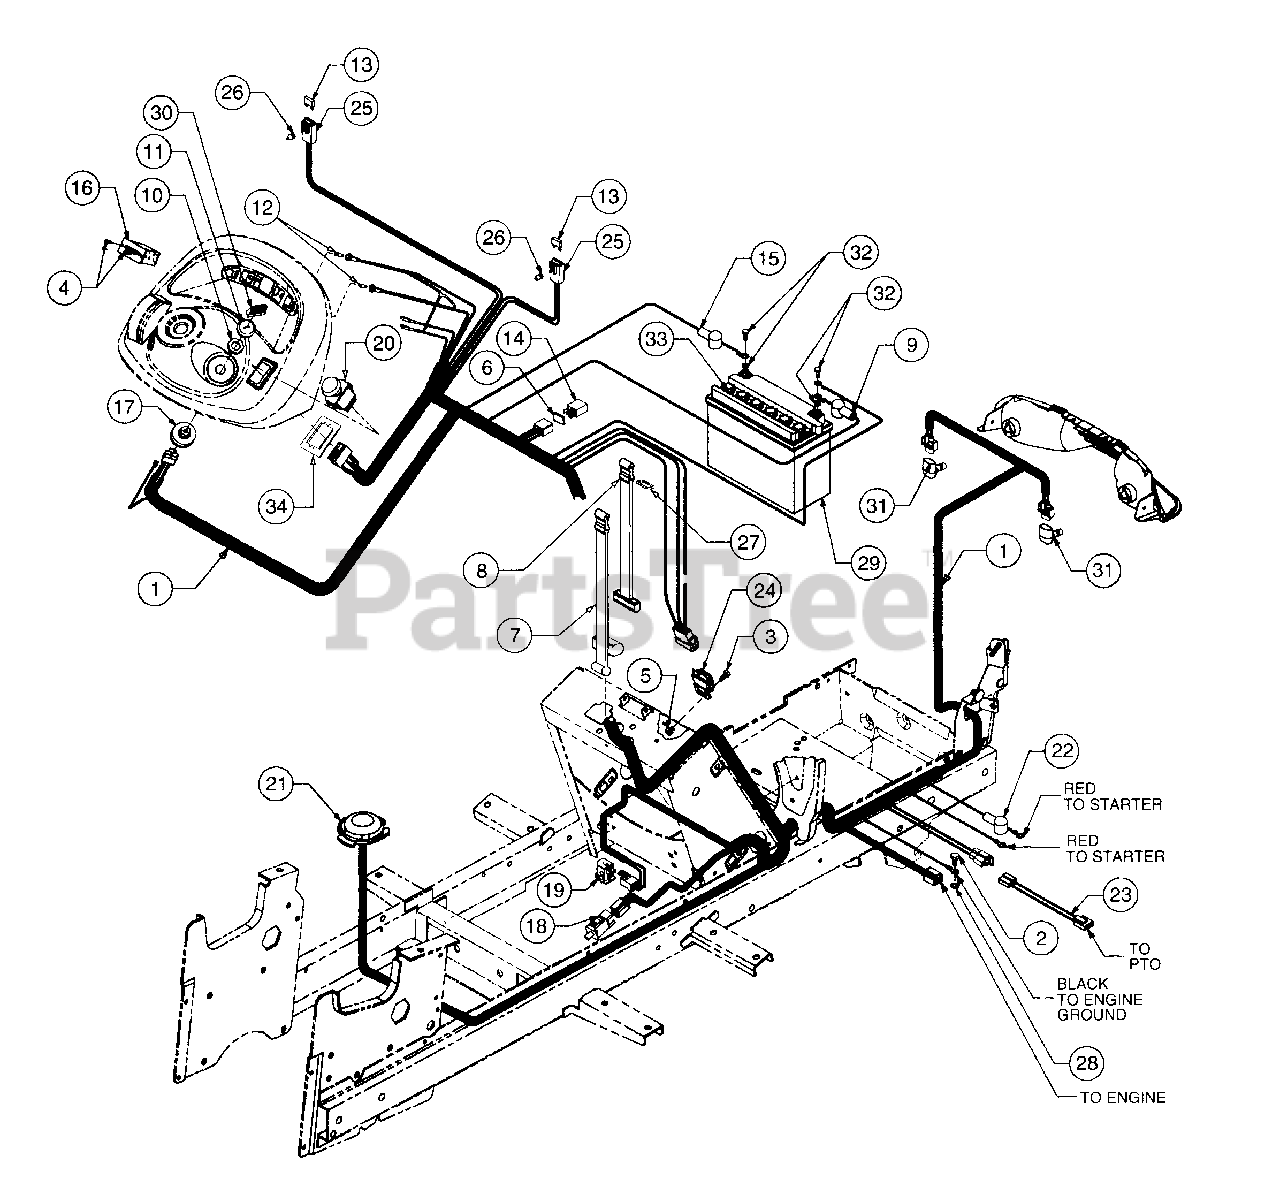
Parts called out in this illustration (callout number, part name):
1	Wire Harness, Main
2	Screw, Hex Cap, 5/16-24 x .62
3	Screw, Hex Cap, 1/4-20 x .625 GR5
4	Screw, Truss Hd Tapp, #6 x .62
5	Nut, Hex Sems, 1/4-20
6	Gasket, Silicone
7	Strap, Battery Retainer
8	Strap, Battery Retainer
9	Cover, Terminal Black
10	Nut, Ignition Switch
11	Cap, Ignition Switch
12	Bulb, Indicator
13	Fuse, 20 Amp
14	Relay
15	Cover, Terminal Red
16	Hour Meter
17	Switch, Ignition
18	Switch, Interlock (Brake)
19	Switch, Snap Mount - Normally Closed
20	Switch, PTO
21	Switch, Seat
22	Cover, Terminal Red
23	Adapter, PTO Harness
24	Module, Voltage Sensor
25	Holder, Fuse
26	Clip, Fuse Holder Mounting
27	Hook, Wire Rectangular
28	Washer, External Lock, 5/16
29	Battery
30	Key, Ignition
31	Bulb, Head Lamp
32	Battery Cable Hardware (Set of 2)
33	Cap, Battery
34	Bracket, PTO Switch Retainer
